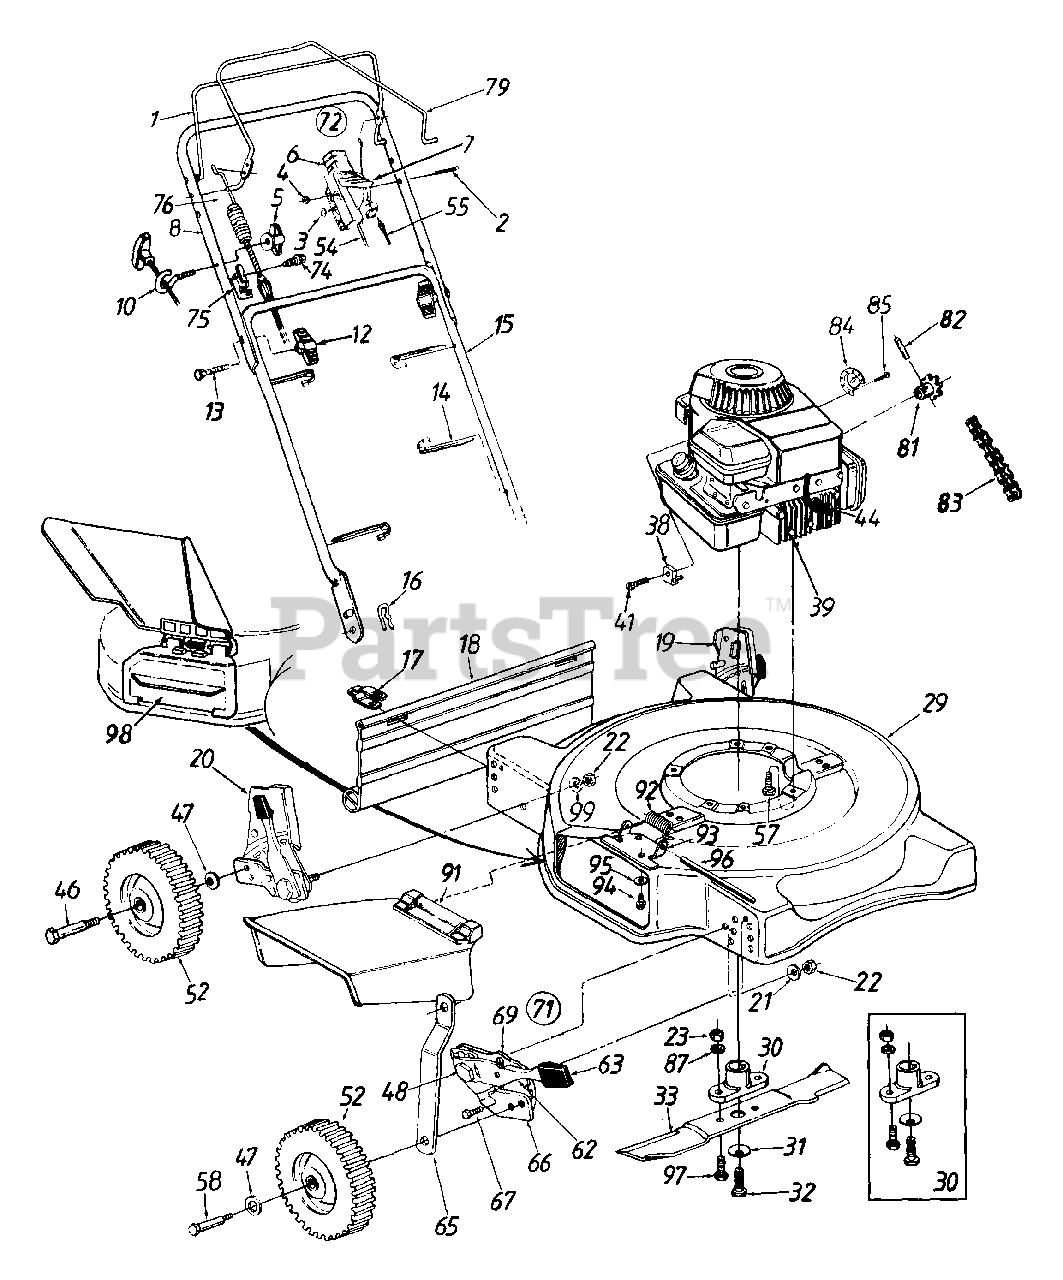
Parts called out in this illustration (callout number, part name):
2	Oval C-Sunk Mach. Scr.
3	Spr. Wash. .66" I.D.
4	Hex L-Nut 1/4 - 20 Thd.
5	Handle Knob 1/4 - 20 Thd.
6	Throttle Body
7	Throttle Lever
12	Hand Knob
13	Curved Hd. Bolt 5/16 - 18 x 2" Lg.
14	Cable Tie
16	Hairpin Cotter
17	Hinge Clip
18	Rear Flap
21	Bell-Wash. .39" I.D. x 1.38"
22	Hex Nut 3/8 - 16 Thd.
23	Hex Nut 3/8 - 24 Thd.
31	Bell-Wash. .39" I.D.
32	Hex Bolt 3/8 - 24 x 1.5" Lg.
33	22" Blade
38	Cable Clamp
39	Engine
41	Hex Wash. Hd. Scr. #10 - 32 x .62" Lg.
44	Spark Plug Boot
46	Rear Axle Bolt
47	Bell-Wash. .400" I.D. x .88"
48	Shld. Bolt .50" Dia. x .357"
52	Front Wheel Ass'y. Comp.
54	Throttle Control Wire - 51"
55	Control Cable - 51"
57	Hex L-Wash. Hd. Scr. 3/8-16 x 1.0" Lg.
58	Front Axle Bolt
62	Spring Lever
63	Spring Lever Knob
67	Hex L-Wash. Hd. AB-Tap Scr. 1/4 x .62" Lg.
69	Index Plate
72	Throttle Box Comp.
74	Hex Wash. AB - Tap Scr. 5/16 x .75" Lg.
75	Cable Brkt.
76	Clutch Cable w/Spring - 47"
82	Spring Pin Spir. 3/16" Dia. x 1" Lg.
83	#48 Chain 1/2" Pitch 50 Links (Endless)
84	Exhaust Deflector
85	Hex AB - Tap Scr. #8 x .5" Lg.
87	L-Wash. 3/8" I.D.
91	Chute Deflector Ass'y.
92	Torsion Spring
93	Adapter Plate
94	Hex Self-Tap Scr. 1/4-20 x .5" Lg.
95	Bell-Wash. 1/4" I.D.
96	Hinge Pin
97	Hex Bolt 3/8-24 x 1" Lg.
98	Mulching Plug
99	Bell-Wash. .39" I.D. x 1.38" O.D.
